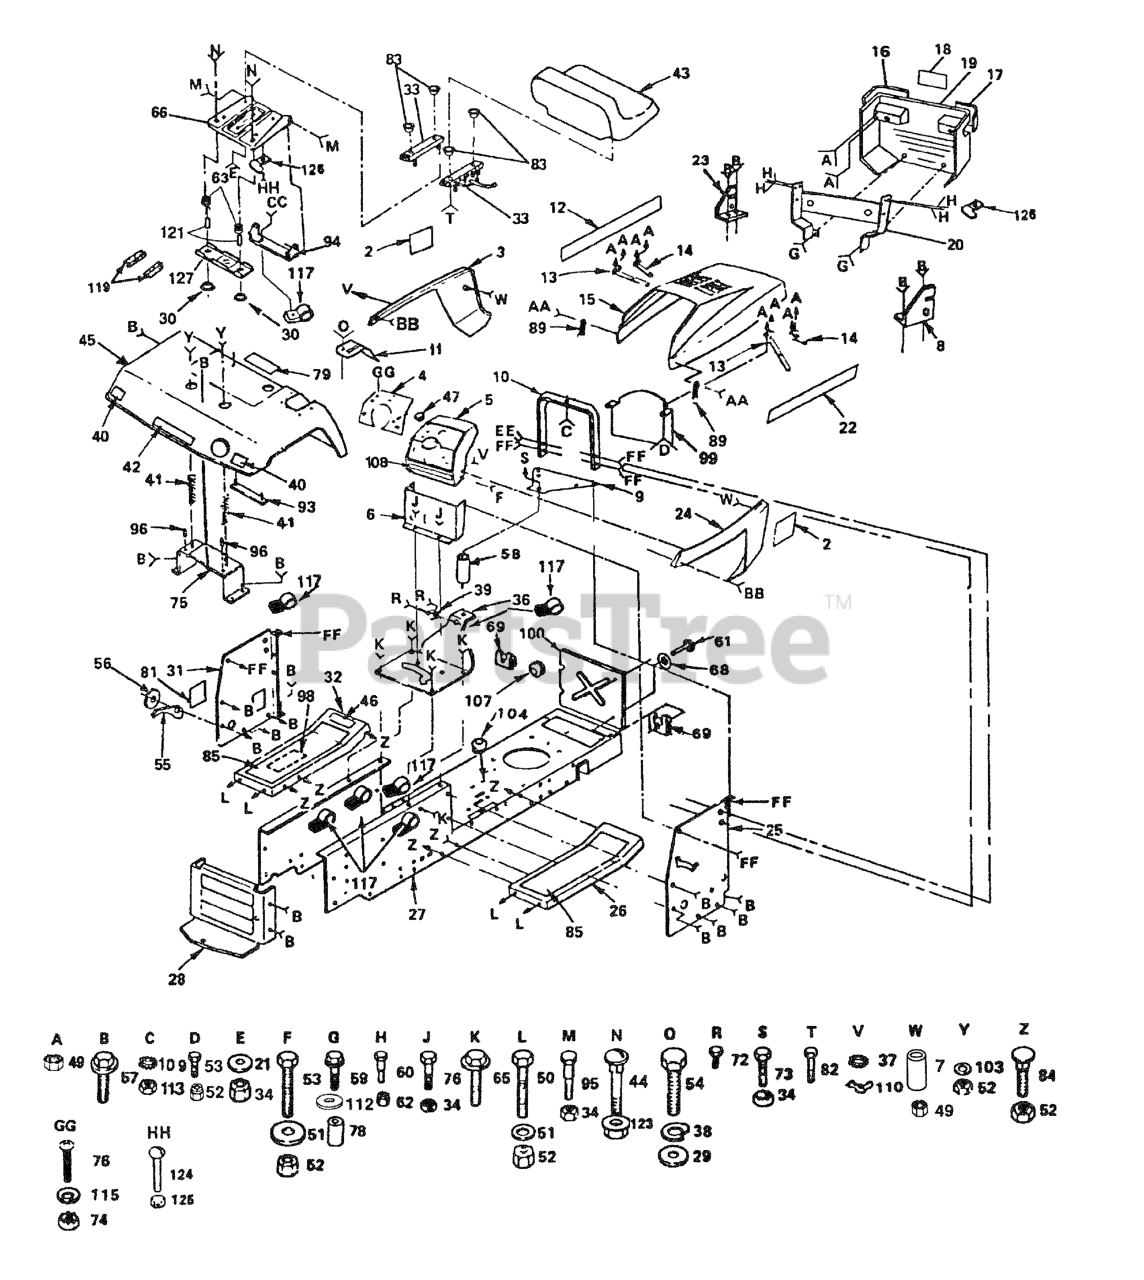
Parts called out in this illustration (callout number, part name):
2	DECAL,SIDE PANEL
3	PANEL,SIDE LH
4	DASHPLATE
5	DASHBOARD
6	DASH LOWER YT NLA
7	SPACER NLA
8	SUPPORT RH YTH
9	PLATE SUPPORT T NLA
10	SUPPORT ASS'Y
11	CONSOLE SHIFTER
12	DECAL,HOOD LH NLA
13	STRAP ASSY LT
14	STRAP ASSY LT
15	HOOD
16	LENS LH
17	LENS RH
18	DECAL,GRILL HUSKY
19	GRILL
20	SUPPORT ASS'Y
22	DECAL,HOOD RH
23	SUPPORT LH YTH
24	PANEL,SIDE RH
25	PANEL LT NLA
26	FOOTREST RH
27	CHASSIS ASSY NLA
28	DRAW BAR
29	Washer 3/16 x 7/16 x 18 Ga.
31	PANEL DASH LH NLA
32	FOOTREST LH
33	SLIDE SET,SEAT
34	LOCKNUT
36	SADDLE
37	LOCKWASHER GT
38	WASHER,LOCK
39	BUSHING LT
40	REFLECTOR-TAIL YT
41	SPRING COMPRESSION
42	DECAL,FENDER HUSQ
43	SEAT
44	Bolt, Carr. 1/4-20 x 1-1/4
47	PLUG BUTTON T
49	NUT
50	BOLT
51	WASHER
53	BOLT
54	SCREW
55	POINTER HGT INDAT
57	SCREW
59	Bolt, Hex 1/4-20 x 1-1/2
60	BOLT T
61	STUD 1/4 TURN
62	NUT.CROWNLOCK.1/4
63	SPRING COMPRESSED
65	SCREW LT
68	RETAINER LT
69	RECEPTACLE LT
72	SCREW LT
73	Bolt-Hex 5/16 -18 x 2 Gr 2
74	NUT
75	BRACKET-FENDER YT
76	Screw,Mach. 5/1 6-18 x 3/4
78	SPACER SPLIT
81	COVER ACCESS
82	Screw, Hex 5/16-18 x 1
84	Bolt-Carriage 3/8-16 x 3/4
85	PAD FOOTREST T
89	LATCH.HOOD.
93	STRAP-FENDER YT
94	BRKT,SEAT PIVOT
95	BOLT, SHOULDER LT
96	NUT-PUSH YT
99	BAFFLE,REAR UPPER
100	SHIELD HEAT HYT
103	WASHER
104	SNAP BUSHING T
107	SNAP BUSHING T
109	Washer, Lock 114 Int. Ext.
110	NUT.WING.LCK.NYL.NOTCH.1/4-20
112	WASHER PM
113	NUT
115	WASHER
117	CLIP T
119	STRIP FORM
121	SPACER SPLIT
123	NUT T
125	Nut, Keps #10-32 UNC
126	CLIP T
127	BRKT SWITCH
